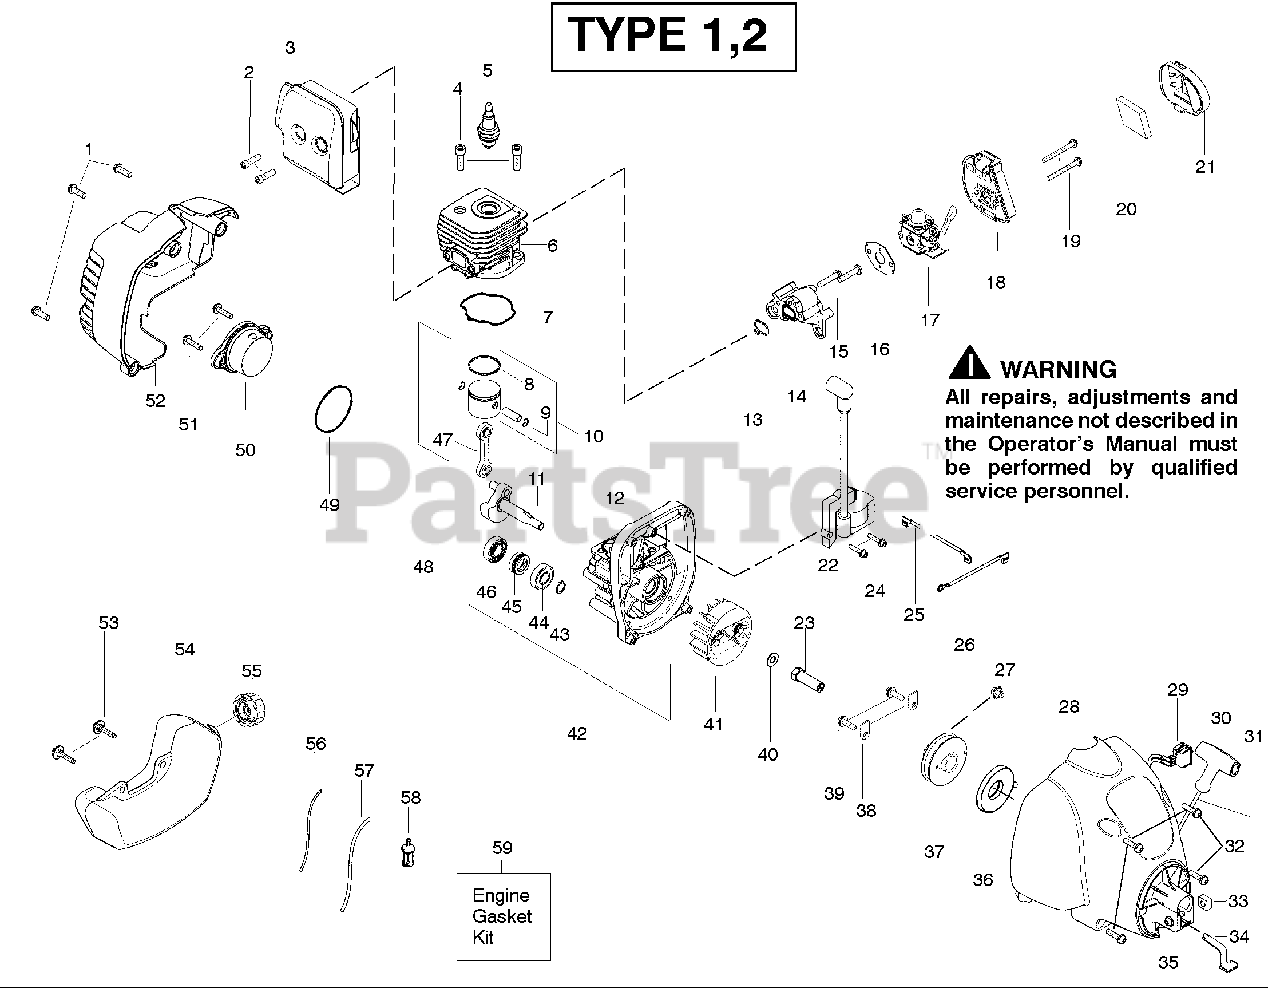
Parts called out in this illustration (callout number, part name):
2	Bolt-Muffler
3	Assy-Muffler/Shield
4	Screw-Cylinder
5	Spark Plug (RCJ 6Y)
6	Cylinder
7	Seal-Cylinder (kit)
8	Piston Ring
9	Retainer-Piston Pin
10	Kit - Piston
11	Assy-Crankshaft
12	Assy-Crankcase
13	Seal-Cyl/Carb.(kit)
14	Adapter-Carb.
16	Gasket-Carb. (kit)
17	Kit-Carb. Zama (C1U-W18)
17	Kit-Carb. Walbro (WT-669)
18	Air Box
20	Foam-Air Filter
21	Cover-Air Box
22	Ignition Module
23	Coupling-Drive
25	Assy-Leadwire
26	Assy-Ground Wire
28	Assy.-Fan Hsg
29	Kit-Switch
30	Handle-Starter
31	Kit - Rope
32	Screw
34	Clip-Spring
36	Spring-Starter
37	Kit-Pulley-Starter
38	Retainer-Pulley
40	Washer-Flat
41	Assy-Flywheel
42	Assy-C'case & C'shaft
43	Retain. Ring-C'shaft
44	Outer Bearing
45	Seal-C'case
46	Inner Bearing
47	Assy-Connecting Rod
48	Kit-Piston/Rod Assy
49	O-Ring-C'case (kit)
50	Assy-Plug
52	Shroud-Rear
53	Retainer-Tank
54	Assy-Fuel Tank
55	Assy-Fuel Cap
56	Kit-Fuel Line (Small)
57	Kit-Fuel Line (Large)
58	Assy-Fuel Pickup
59	Kit-Engine Gasket
